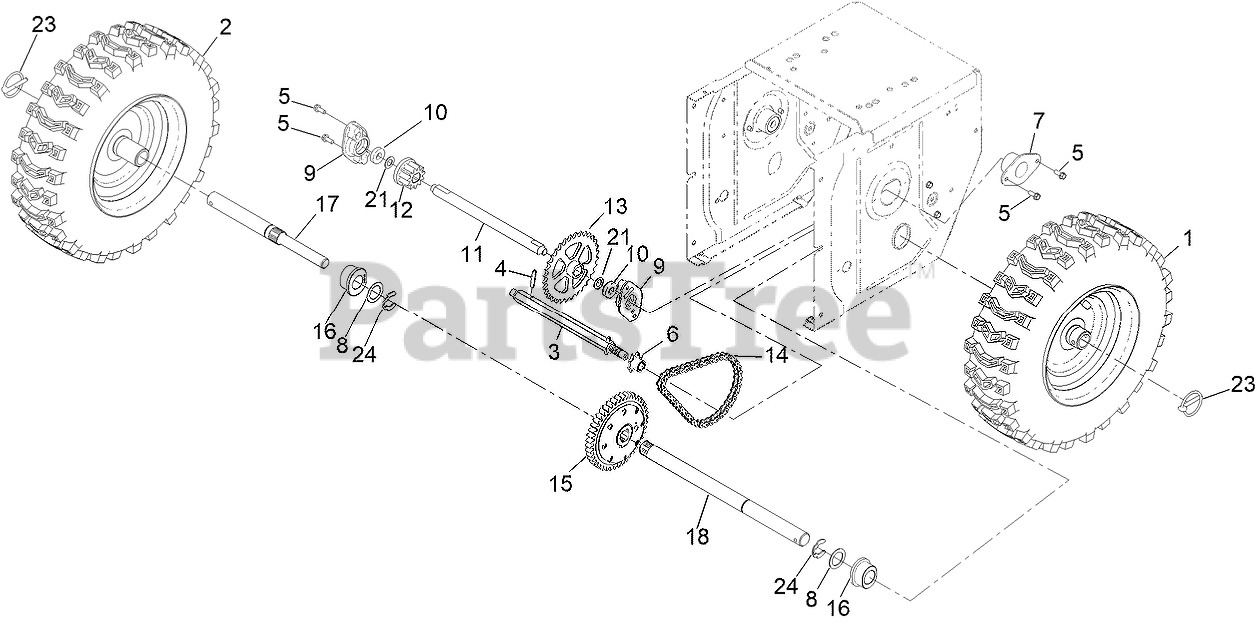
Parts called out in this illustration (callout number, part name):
1	LH WHEEL AND TIRE ASM
2	RH WHEEL AND TIRE ASM
3	SHAFT-HEX
4	PIN-ROLL, SLOTTED
5	SCREW-HWH
6	GEAR-PINION, 8 TOOTH
7	RETAINER-BEARING
8	WASHER-THRUST
9	RETAINER-BEARING, INTERMEDIATE
10	BEARING-WHEEL
11	SHAFT-INTERMEDIATE
12	TOOTH-GEAR, 11
13	SPROCKET-32T
14	CHAIN-ROLLER
15	TRANSMISSION-GT, DI300
16	BUSHING-AXLE
17	AXLE-RT, HD
18	AXLE -LT, HD
21	WASHER-PLAIN
23	PIN-KLIK
24	RING-RETAINING
